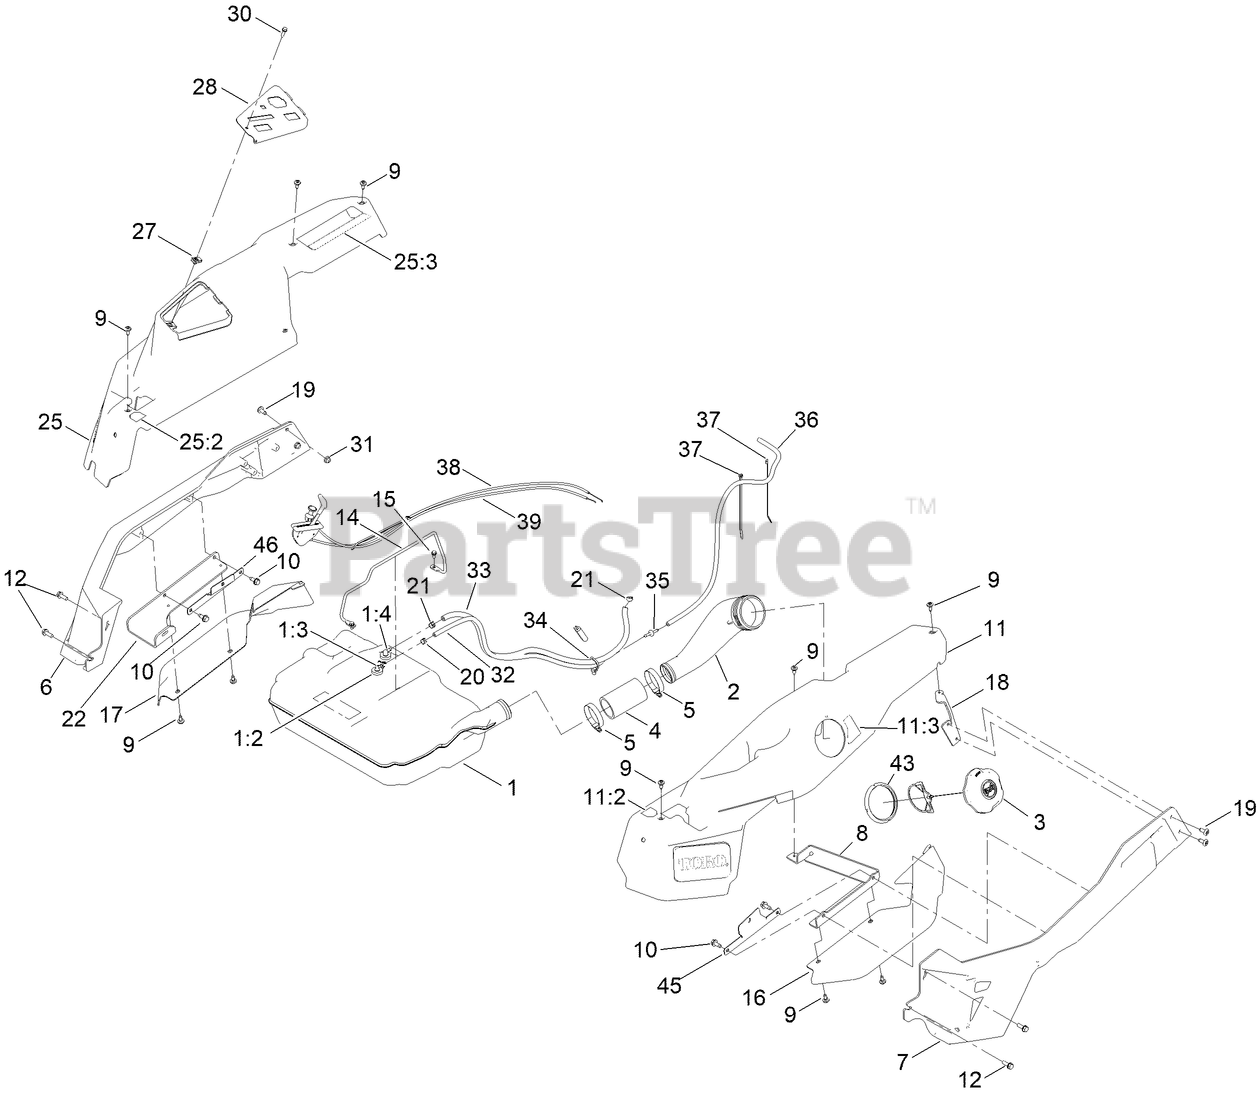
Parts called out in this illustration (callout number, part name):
1	TANK-FUEL ASM
1:2	BUSHING
1:3	FITTING-ELBOW 90
1:4	FITTING - PICKUP, FUEL
2	NECK-FILLER, FUEL
3	CAP-FUEL, RATCHETING
4	HOSE-FILLER, FUEL
5	CLAMP-HOSE
6	CAST-TUBE, RH [RED]
7	CAST-TUBE, LH [RED]
8	MOUNT-POD BRACKET LH
9	SCREW-SHOULDER
10	SCREW-HWHTF
11	POD ASM - LH W/DECALS
11:2	DECAL-CONTROL LEVER, LH
11:3	DECAL-FUEL FILL
12	SCREW-TAPTITE
14	ROD-HOLD DOWN
15	SCREW-HWH
16	FENDER-TIME CUTTER, LH
17	FENDER-TIME CUTTER, RH
18	BRACKET-REAR POD, LH
20	CLAMP-HOSE
21	CLAMP-HOSE
22	BRACKET-MR SPRING
25	POD ASM - RH , MR W/DECALS
25:2	DECAL-CONTROL LEVER, RH
25:3	DECAL - MYRIDE
28	PANEL-CONTROL
30	SCREW-HWH
31	NUT-HF
32	HOSE-FUEL
33	HOSE-FUEL
34	CLIP-TIE
35	ADAPTER ORIFICE
36	HOSE-LP
37	TIE-CABLE
38	CABLE-THROTTLE
39	CABLE-CHOKE
43	RING-RETAINING
45	BRACKET-ALIGNMENT, POD LH
46	BRACKET- ALIGNMENT, POD RH MR
